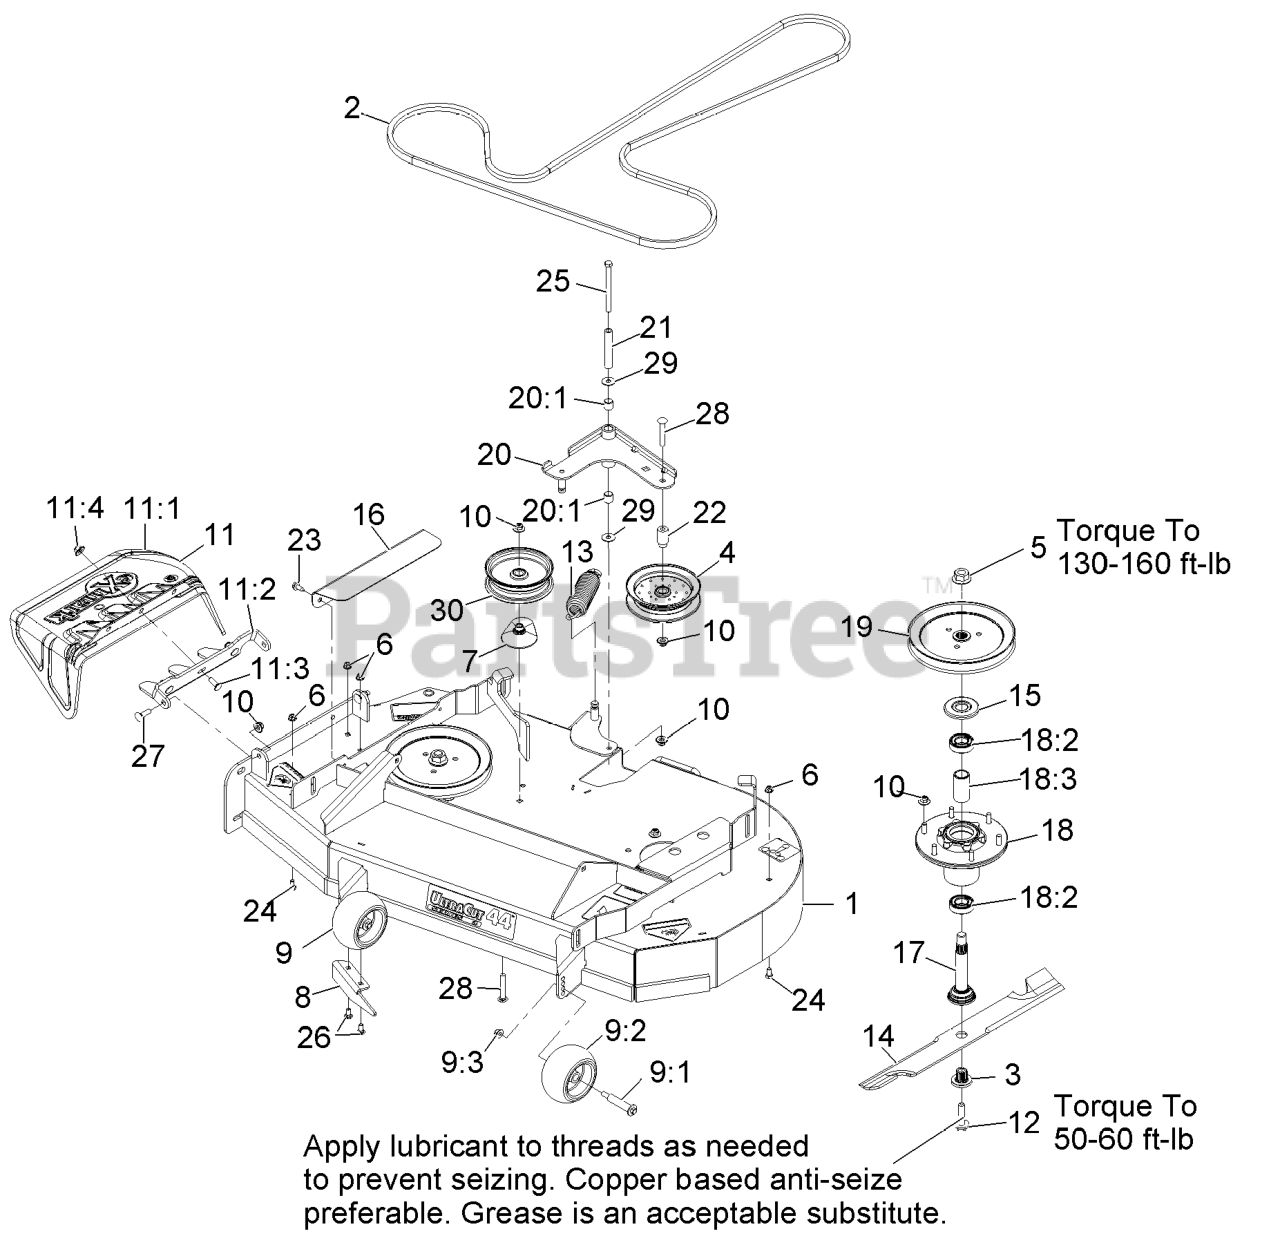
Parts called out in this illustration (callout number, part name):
1	ASM-DECK W/DECALS 44
2	BELT - V, B
3	BUSHING,SPLINED
5	NUT-FLANGE
6	NUT-HF, NI
7	SPACER-PULLEY
8	BAFFLE-DISCHARGE
9	ANTI-SCALP ROLLER KIT
9:1	BOLT-SHOULDER
9:2	ROLLER-SCALP, ANTI
9:3	NUT-HF, NI
10	Nut-Nyloc 3/8-16 Flg
11	ASM,DISCHARGE CHUTE
11:1	CHUTE,DISCHARGE
11:2	BRACKET,DISCHARGE CHUTE
11:3	SCREW-CARR
11:4	Nut-Nyloc 3/8-16 Flg
12	SCREW,SEMS 1/2-20 X 2.19
14	Blade-Notched, 22.25
14	Blade-Mulch, 22.25
15	GUARD,BEARING TOP .989
16	COVER,BELT
17	ASM-SPINDLE AND SEAL
18	ASM-CUTTER HSG WITH BEARINGS
18:2	BEARING-BALL
18:3	SPACER-BEARING
19	SHEAVE-BLADE DRIVE, 8.40
20:1	SLEEVE-BEARING
21	BUSHING
22	BUSHING-IDLER
23	Screw-HWH 5/16-18 X 3/4 Tf
24	SCREW-HH
25	SCREW-HH
26	BOLT-CARR
27	BOLT-CARR
28	SCREW-CARR
